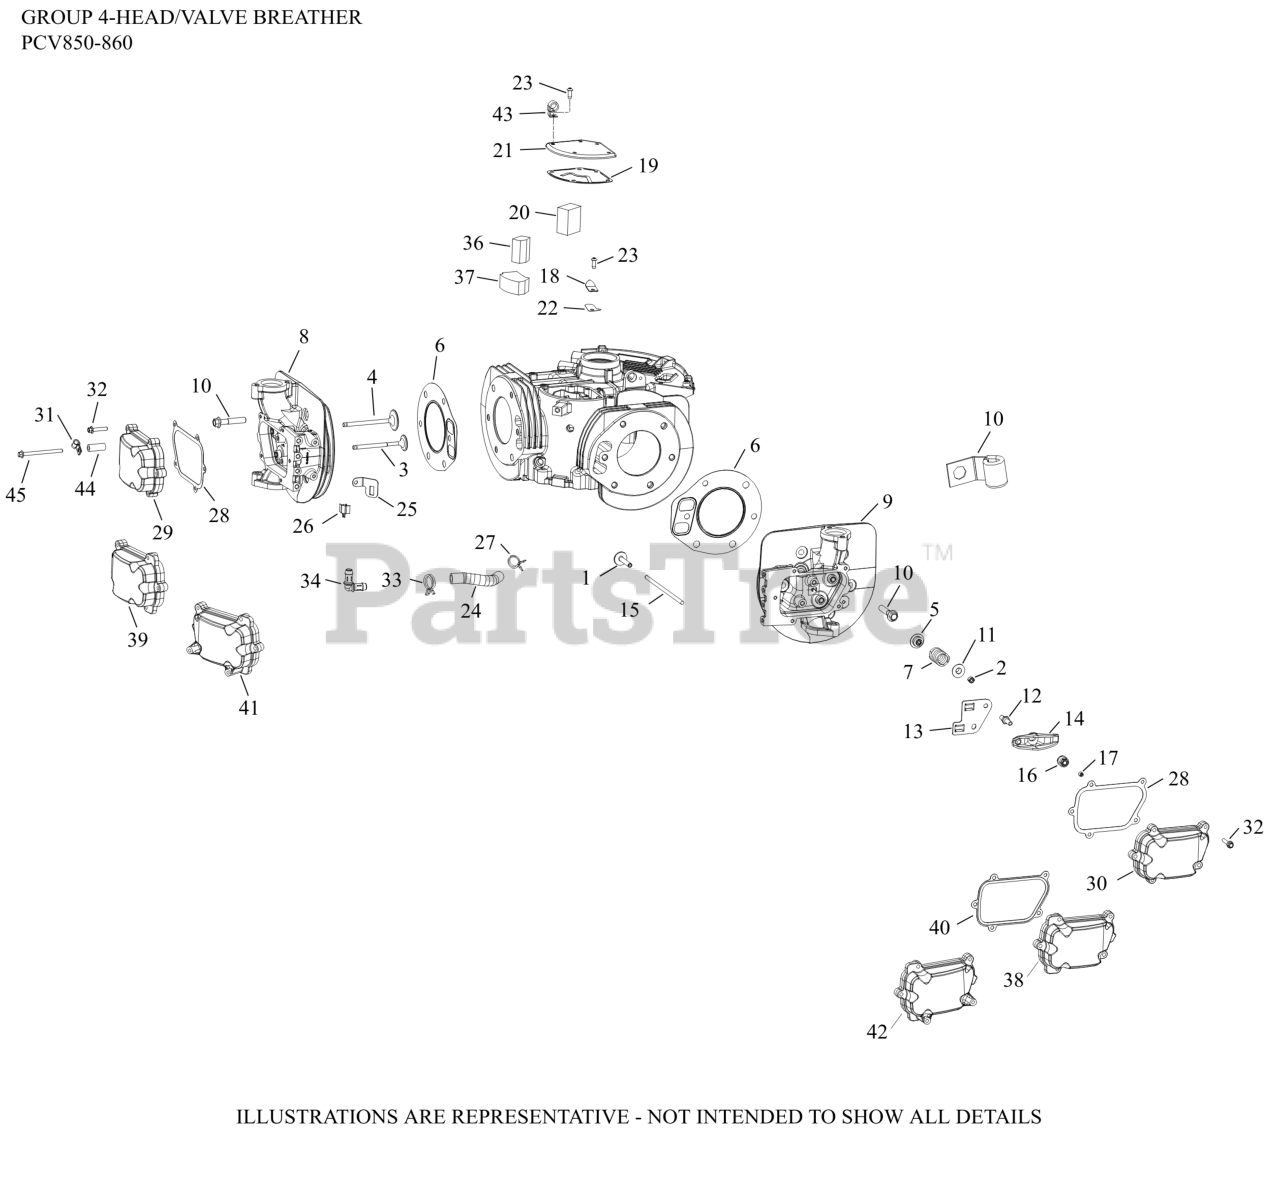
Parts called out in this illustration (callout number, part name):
1	TAPPET, COATED
2	KIT, RETAINER
3	VALVE, EXHAUST
4	VALVE, INTAKE
5	SEAL, VALVE STEM
6	KIT, HEAD GASKET (824)
7	SPRING, VALVE
10	SCREW, HEAD
11	CAP, VALVE SPRING
12	STUD, ROCKER
13	PLATE, PUSHROD GUIDE
14	ARM, ROCKER
15	ROD, PUSH
16	PIVOT, ROCKER ARM
17	SCREW, SET
19	GASKET, BREATHER-(#1904118S)
21	COVER, BREATHER
22	REED, BREATHER
23	SCREW, BUTTON HEAD
24	HOSE, BREATHER
25	BRACKET, OXYGEN SENSOR
26	CLIP, O2 SENSOR
27	CLAMP, HOSE
33	CLAMP, HOSE
NI	RETAINER, REED
NI	GASKET, VALVE COVER
NI	FILTER, BREATHER MEDIA (LOWER HALF)
NI	FILTER, BREATHER MEDIA (UPPER HALF)
NI	KIT, VALVE COVER #1
NI	KIT, VALVE COVER #2
NI	FITTING, 90 DEGREE
NI	CABEZA CILINDRO NO.1/KIT,CYLINDER HEAD#1
NI	KIT,CYLINDER HEAD#2
NI	CLIP, CABLE (KM)
NI	SCREW, FLG M6X1.0X80
